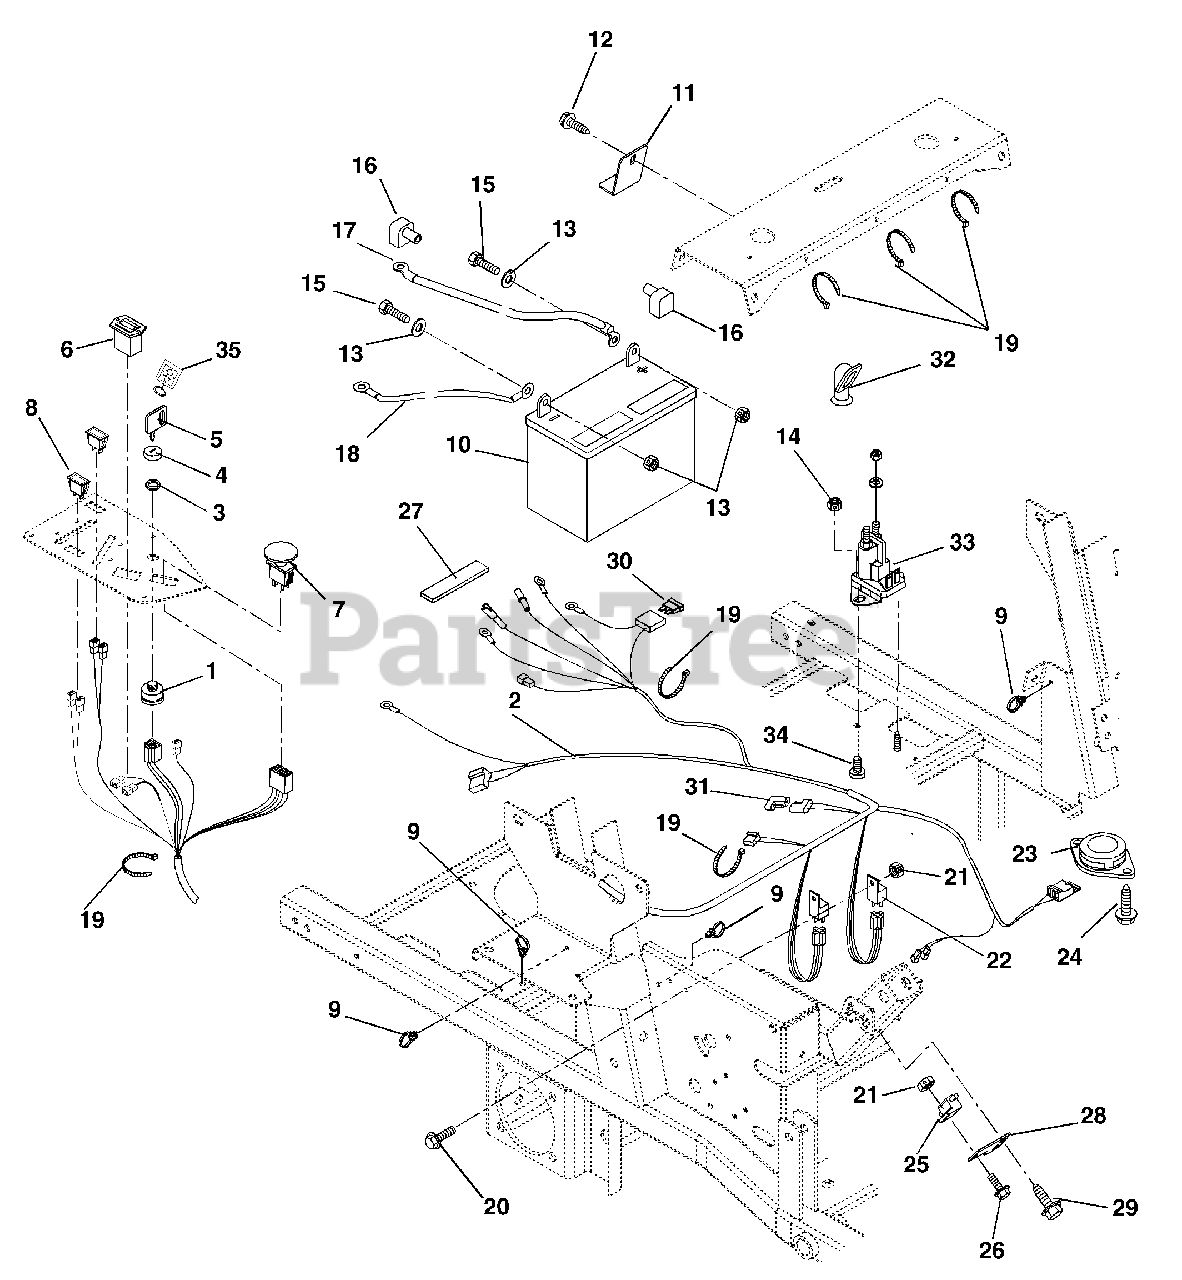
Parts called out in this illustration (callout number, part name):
1	Key Switch (029, 030, 032, 033, 034, 035)
1	Key Switch (020)
2	Harness, Z 6-Pin Wiring (020, 029, 030, 034, 035)
2	Harness, Wiring-EFI (032, 033)
3	Nut-Panel .562-24
4	Cap-Ignition Switch
5	Key-with Cap
6	Hour Meter
7	Switch-Clutch With Retainer Ring
8	Light-Indicator Kit (020, 029, 030, 034, 035)
8	Light-Indicator Kit (032, 033)
9	Tube Clip .75 (020, 029, 030, 034, 035)
9	Tube Clip 1 1/2 (032, 033)
10	Battery with Tube
11	Clamp-Battery Hold Down
12	Screw-Tapping .25-20 x .50 Hex Washer Head
13	Washer-Flat-Steel .281 x .620 x .065
14	Nut-Locking-Center .25-20
15	Bolt-Hex .25-20 x .75 Grade 5
16	Insulator
17	Positive Cable 22"
18	Ground Cable
19	Cable Tie
20	Screw-Machine 10-24 x .50 Hex Washer Head (020, 029, 030, 034, 035)
20	Screw-Machine 10-24 x .50 Hex Washer Head (032, 033)
21	Nut-Locking-Nylon 10-24 With Insert
22	Relay
23	Seat Switch
24	Screw-Tapping 12-24 x .50 Hex Washer Head
25	Switch-Single Pole
26	Screw-Machine 10-24 x .75 Hex Washer Head
27	Pad-Battery
28	Plate-Switch
29	Screw-Tapping .38-16 x .50 Hex Washer Head
30	Fuse, 30 Amp
31	Molded Diode Plug-Black 1-Amp
32	Insulator, Boot
33	Solenoid
34	Bolt-Hex .25-20 x .50 Grade 5
35	Key Chain
